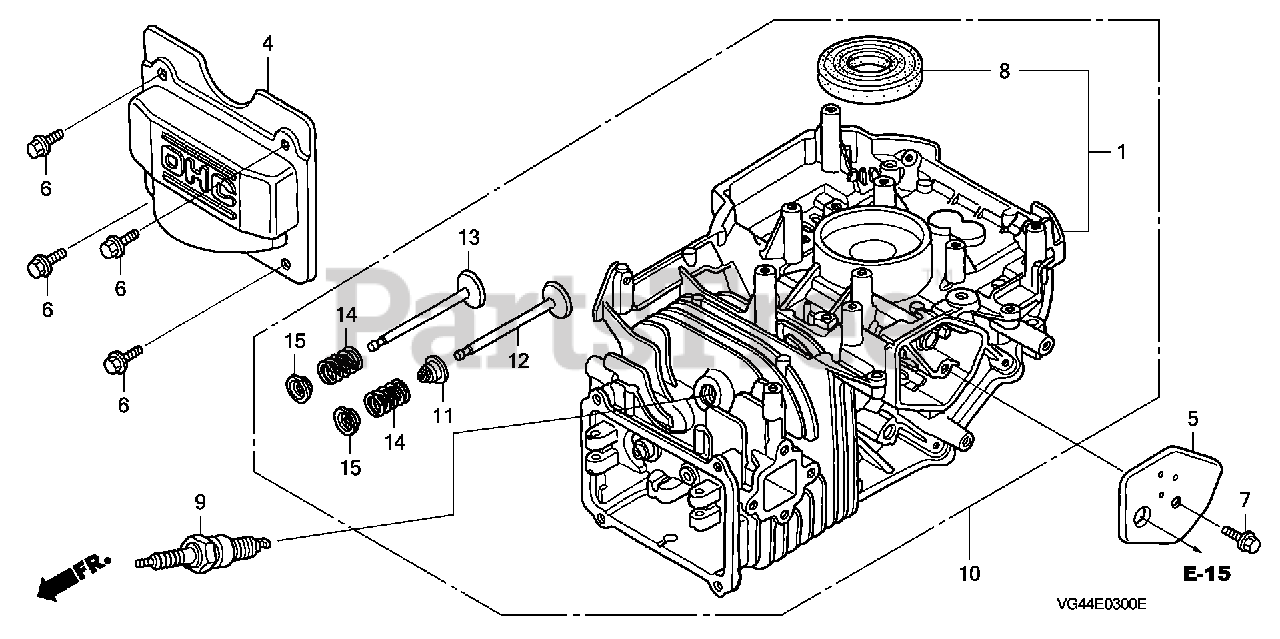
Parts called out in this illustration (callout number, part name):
4	COVER, CYLINDER HEAD
4	COVER, HEAD
5	COVER, BREATHER (BREATHER VALVE ASSY.)
6	BOLT, FLANGE (6X12) (CT200)
7	BOLT, FLANGE (6X14) (CT200)
8	OIL SEAL (25.4X62X6)
9	SPARK PLUG (BPR6ES) (NGK)
10	CYLINDER ASSY.
11	SEAL, VALVE STEM
12	VALVE, IN. (ROCKNEL)
13	VALVE, EX. (L8E)
13	VALVE, EX. (C8E)
14	SPRING, VALVE
15	RETAINER, IN. VALVE SPRING
15	RETAINER, VALVE SPRING
